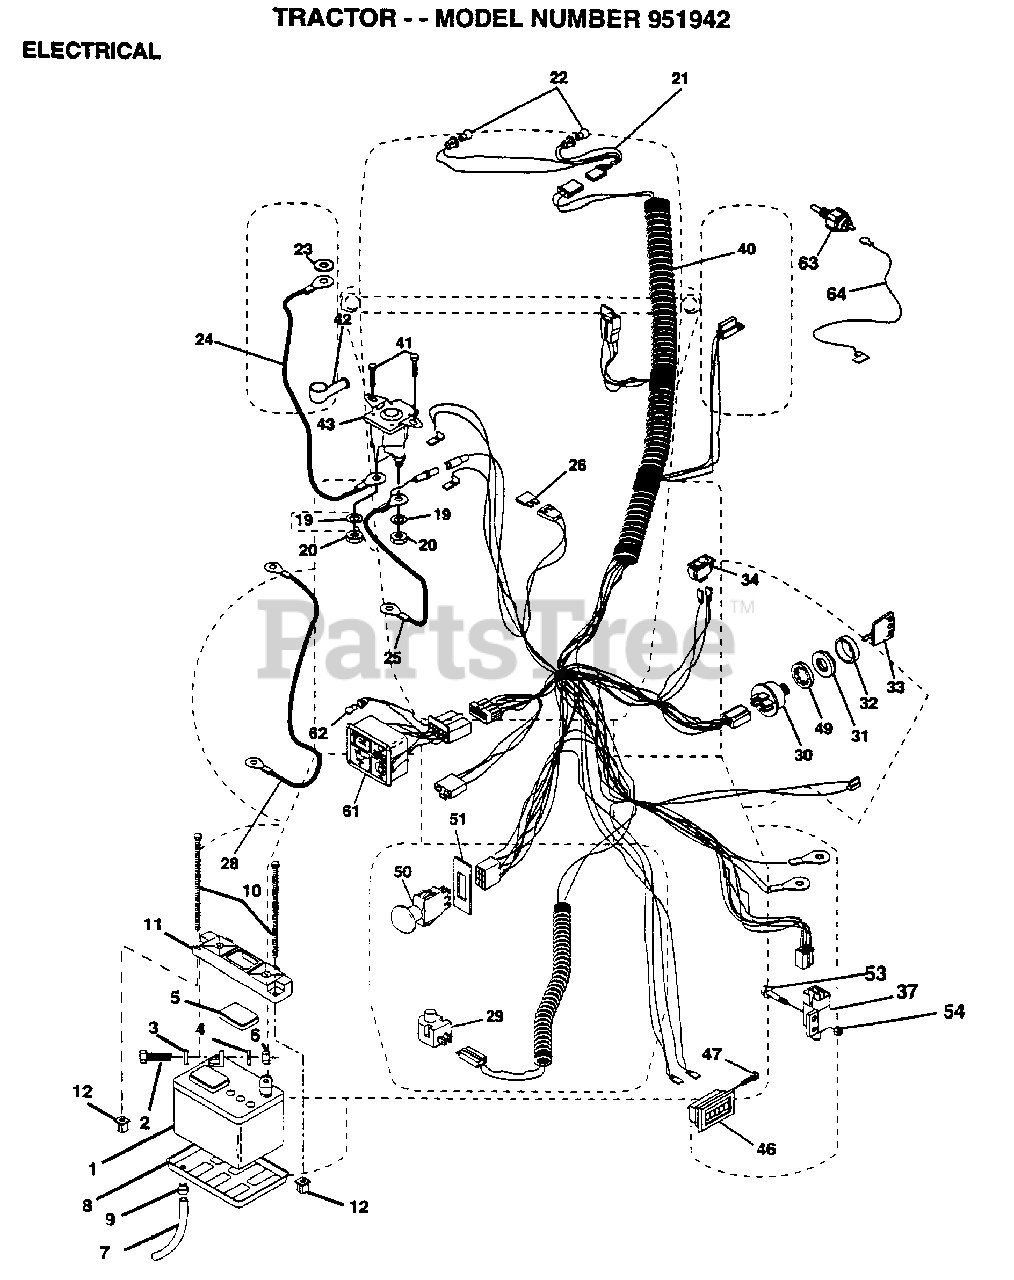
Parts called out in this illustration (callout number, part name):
2	BOLT LT
3	LOCKWASHER
4	WASHER
5	"CAP,BATTERY "
7	"DRAIN TU T, BATT"
8	"TRAY T, BATTERY"
9	HOSE CLAMP T
20	NUT
21	"HARNESS,LIGHT SOC"
22	HEADLAMP BULB
23	LOCKWASHER
24	"CABLE T, BATTERY"
25	CABLE.6GA.12.5.
26	FUSE HYT
28	CABLE T
29	SWITCH SEAT
32	COVER KEY SWITCH
33	KEY MLD GEN DELTA
34	SWITCH LT
37	SWITCH INTERLOCKT
40	HARNESS.IGN.GT.EL
41	SCREW
46	HOUR METER T
47	SCREW
49	LOCKWASHER
51	RING RETAIN PTO
53	SCREW
54	"NUT,KEPS"
61	LIGHT.PKG.ASM.
62	BULB LIGHT T
63	SWITCH OIL KOHLER
64	WIRE LEAD KOHLER
